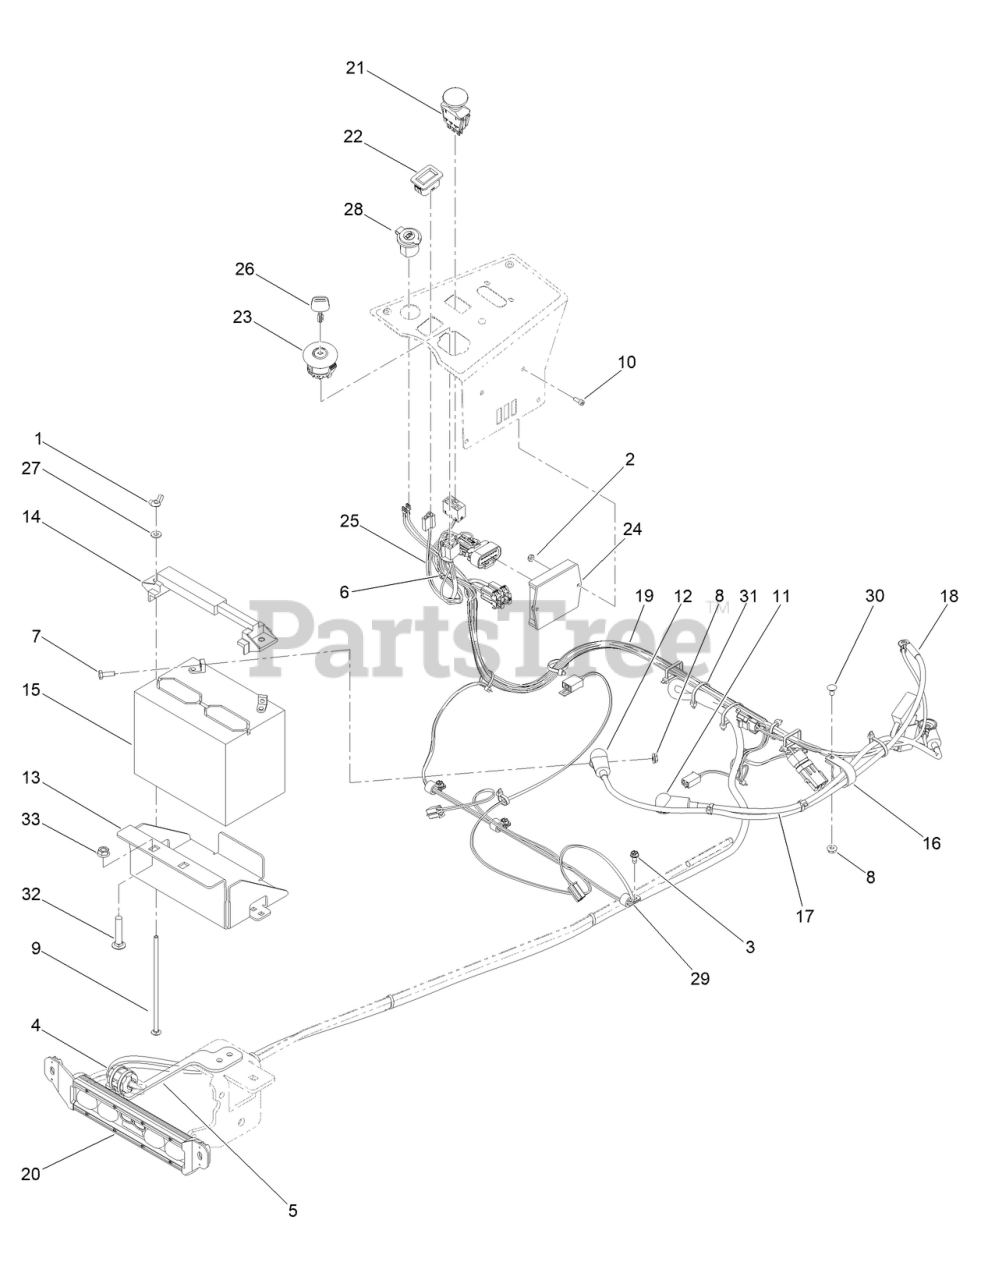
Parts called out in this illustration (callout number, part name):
1	NUT-WING
2	NUT-LOCK
3	SCREW-HWH
4	FAIR-RITE ROUND CABLE SNAP-IT SIZE B
5	FAIR-RITE BRACKET PAINTED
6	6IN (40 LB) CABLE TIE NYLON UV
7	SCREW-HH
8	1/4-20 HEX FLANGE NUT
9	1/4-20 X 7 CARRIAGE BOLT ZINC
10	10-24 X 1/2 SOCKET C/S 18-8 SS
11	3.15 LGTH STRAIGHT INSUL TERM COVER RED
12	STRAIGHT INSULATING TERMINAL COVER
13	MWR BATTERY BOX
14	BATTERY HOLD DOWN
15	12 VOLT START BATTERY 300CCA
16	1-1/4IN CUSHIONED LOOP CLAMP BLACK
17	MWR POSITIVE BATTERY CABLE 25IN
18	MWR NEGATIVE CABLE 28
19	HARNESSVANGUARD 26HP + KAWI 852CC/999CC
20	FULL BEAM WITH LIGHTED HELMET LIGHT BAR
21	PTO SWITCH
22	HOUR METER
23	IGNITION SWITCH
24	INTERLOCK MODULE
25	MWR KEYSWITCH JUMPER HARNESS
26	2023 MWR KEY
27	WASHER-FLAT
28	12 VOLT AUXILLIARY PLUG
29	CLAMP-R
30	SCREW-CARR
31	TIE-CABLE
32	SCREW-CARR
33	3/8-16 HEX FLANGE NUT W/SERR ZINC YELLOW
